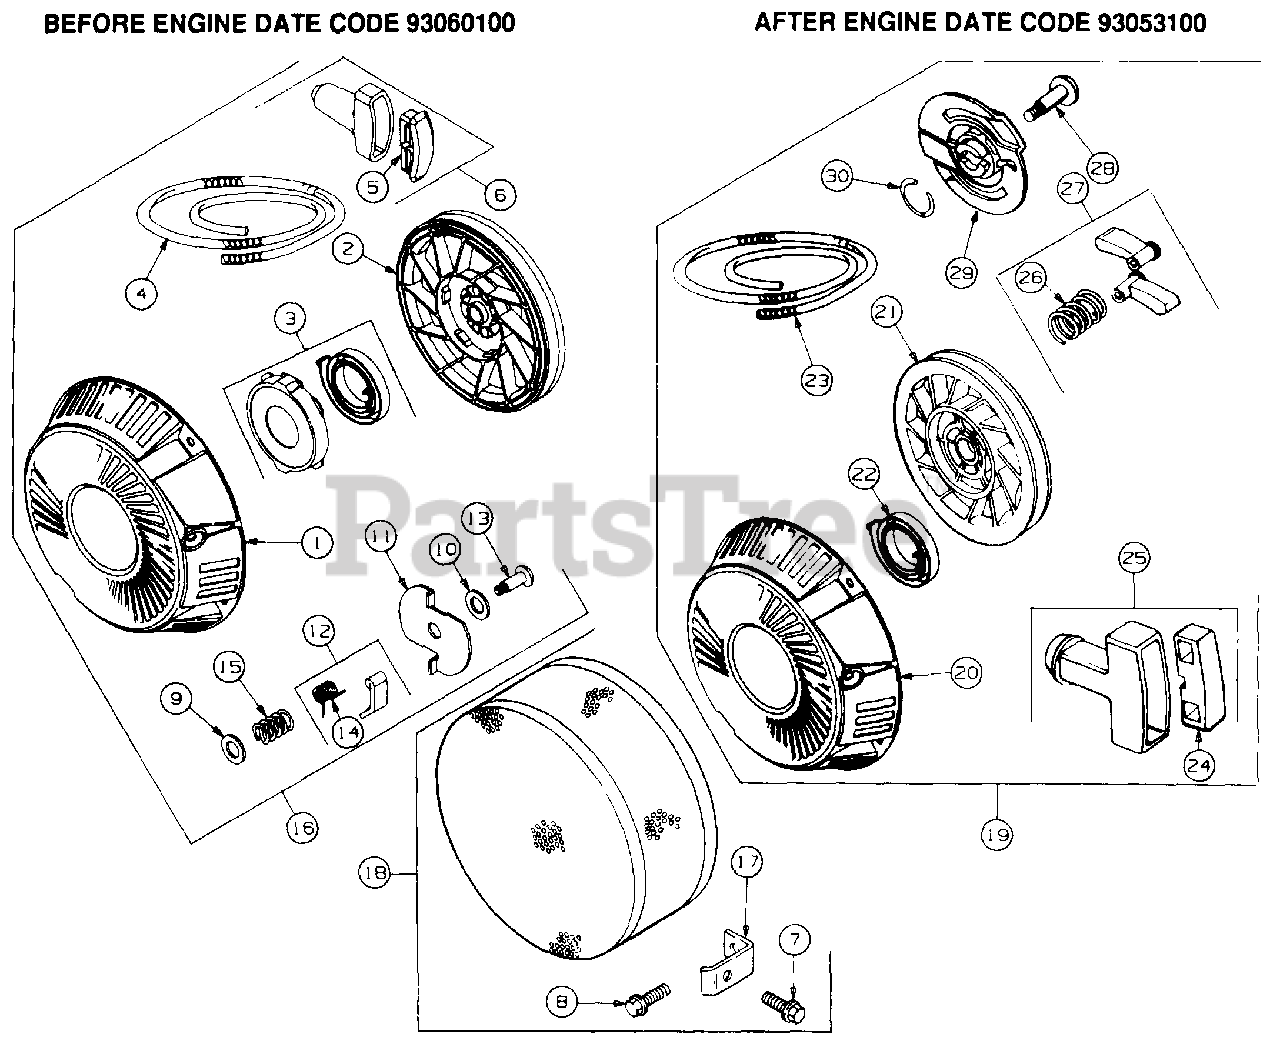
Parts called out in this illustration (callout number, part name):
1	Housing, Starter
2	Pulley, Rewind Starter
3	Spring, Rewind Starter
4	Rope Starter (Cut to 69-1/2")
5	Insert, Starter Handle
6	Handle, Rewind Starter
7	Screw, Sem
8	Screw, Hex Hd (Bracket Mtg)
9	Washer, Pulley
10	Washer, Retainer
12	Dog, Starter
13	Screw, Pan Head
14	Spring, Dog
15	Spring, Torsion
16	Starter Assy, Rewind
17	Bracket, Debris Guard
18	Screen Assy, Debris
19	Starter Assy, Rewind w/Starter Hub
20	Housing, Starter
21	Pulley, Rewind Starter
22	Spring, Rewind Starter
23	Rope Starter (Cut to 78-3/4)
24	Insert Starter Handle
25	Handle Rewind Starter
26	Spring, Dog
27	Dog, Starter
28	Screw, Retainer
29	Retainer
30	Ring, Retaining
